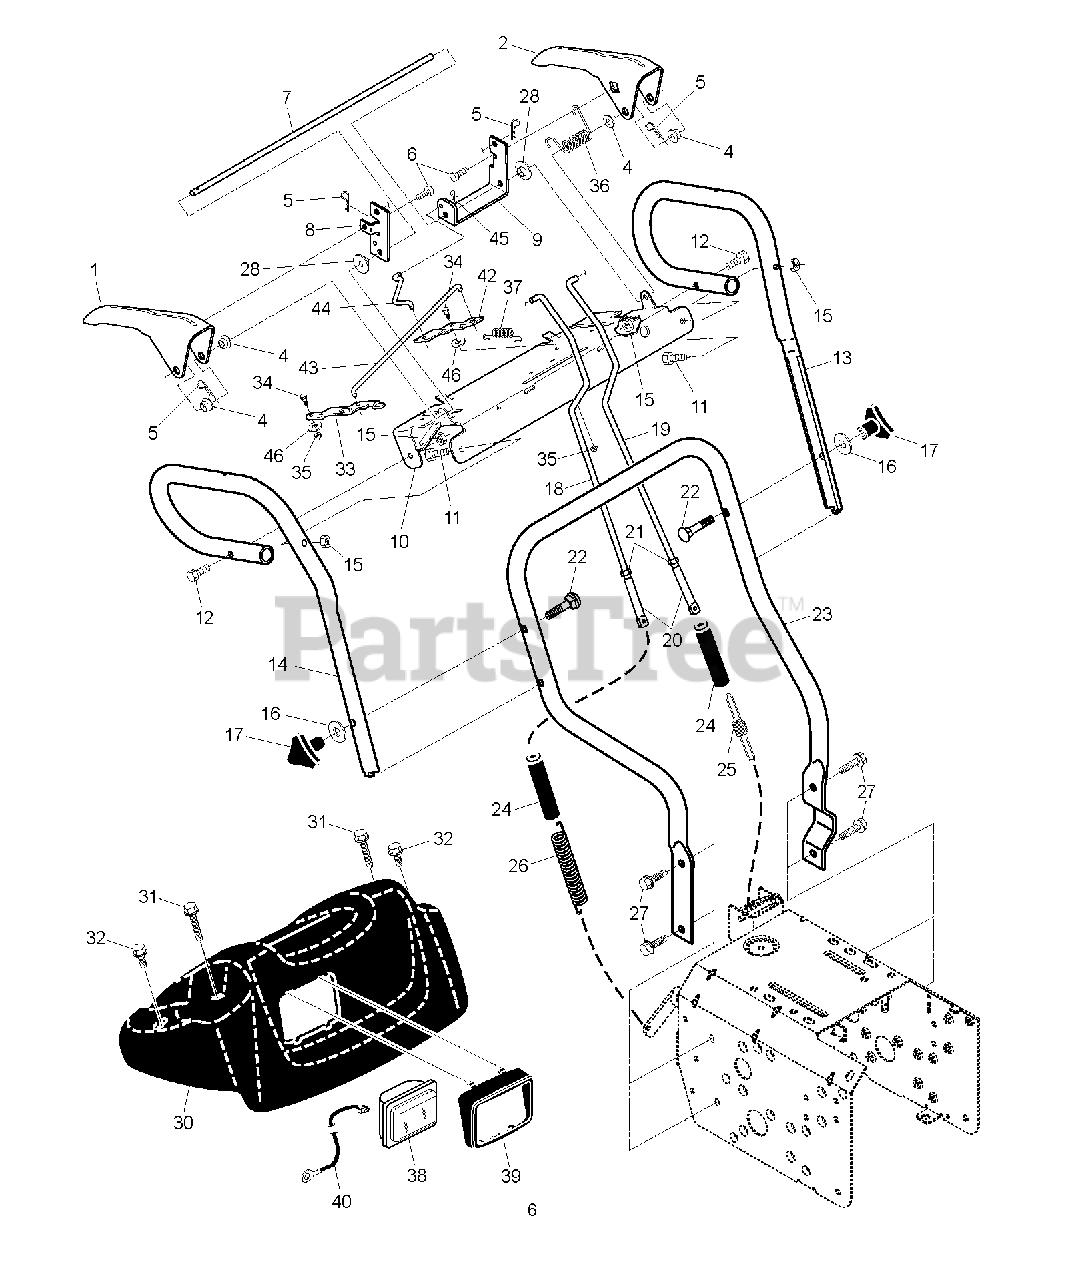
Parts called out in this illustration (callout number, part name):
1	LEVER, AUGER CONTROL, RH
2	LEVER, TRACTION DRIVE CONTROL,
4	BUSHING, FLANGE
5	SPRING RETAINER
7	ROD.INTERLOCK
8	ARM,IMPELLER ROD
9	ARM,TRACTION ROD
10	PANEL.CONTROL
11	HEX BOLT
15	NUT, LOCK 5/16-18
17	KNOB.HANDLE.3/8.TRI-POINT.BLAC
18	ROD.AUGER.CONTROL
19	ROD.CABLE.TRACTION.LONG
20	ROD, END CONTROL
21	JAM NUT TI
22	BOLT 3/8-16 X 2-1/4
23	TUBE.LOWER.HANDLE.24.BLACK
24	SLEEVE, SPRING
25	SPRING, TRACTION DRIVE
26	SPRING, AUGER CONTROL
27	SCREW 3/8-16X1
28	BUSHING, IDLER PIVOT
30	PANEL.CONSOLE.HEADLIGHTS
31	SCREW, HEX HD TAPPING #10-24 1
32	SCREW, HEX HEAD, TAPPING
33	LATCH.INTERLOCK
34	BOLT SHOULDER
35	NUT **
36	RP SPRING, TORSION
37	SPRING LATCH
38	HEADLIGHT, HALOGEN
39	BEZEL.HEADLIGHT.BLACK
40	HARNESS.WIRE.HALOGEN
42	LEVER.INTERLOCK
43	ROD.LATCH.INTERLOCK
44	ROD.ASM INTERLOCK
45	RETAINER CLIP
46	THRUST WASHER
